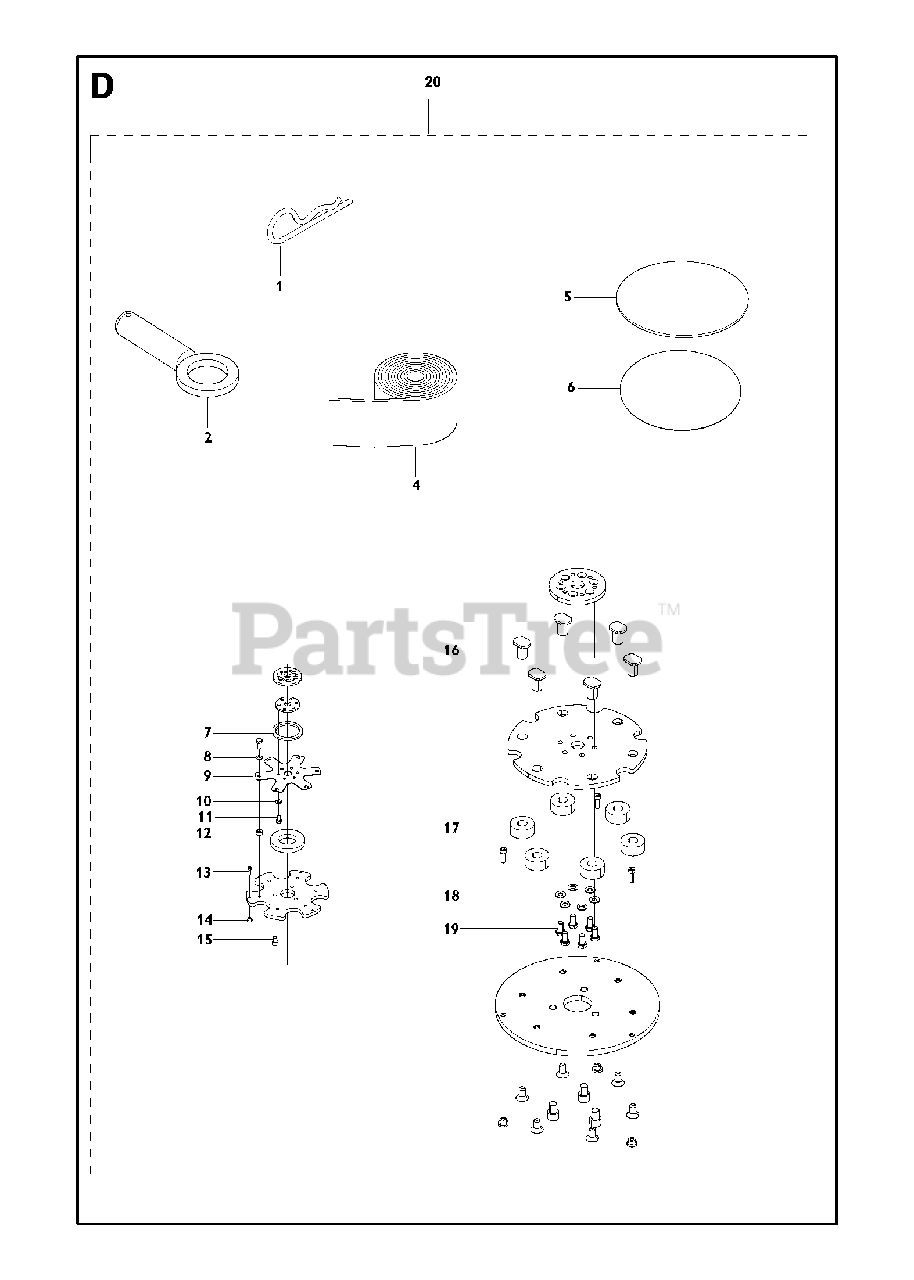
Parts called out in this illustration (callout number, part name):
1	SPRING COTTER
8	WASHER
10	WASHER
11	SCREW EHHM
18	WASHER
19	SCREW EHHM
